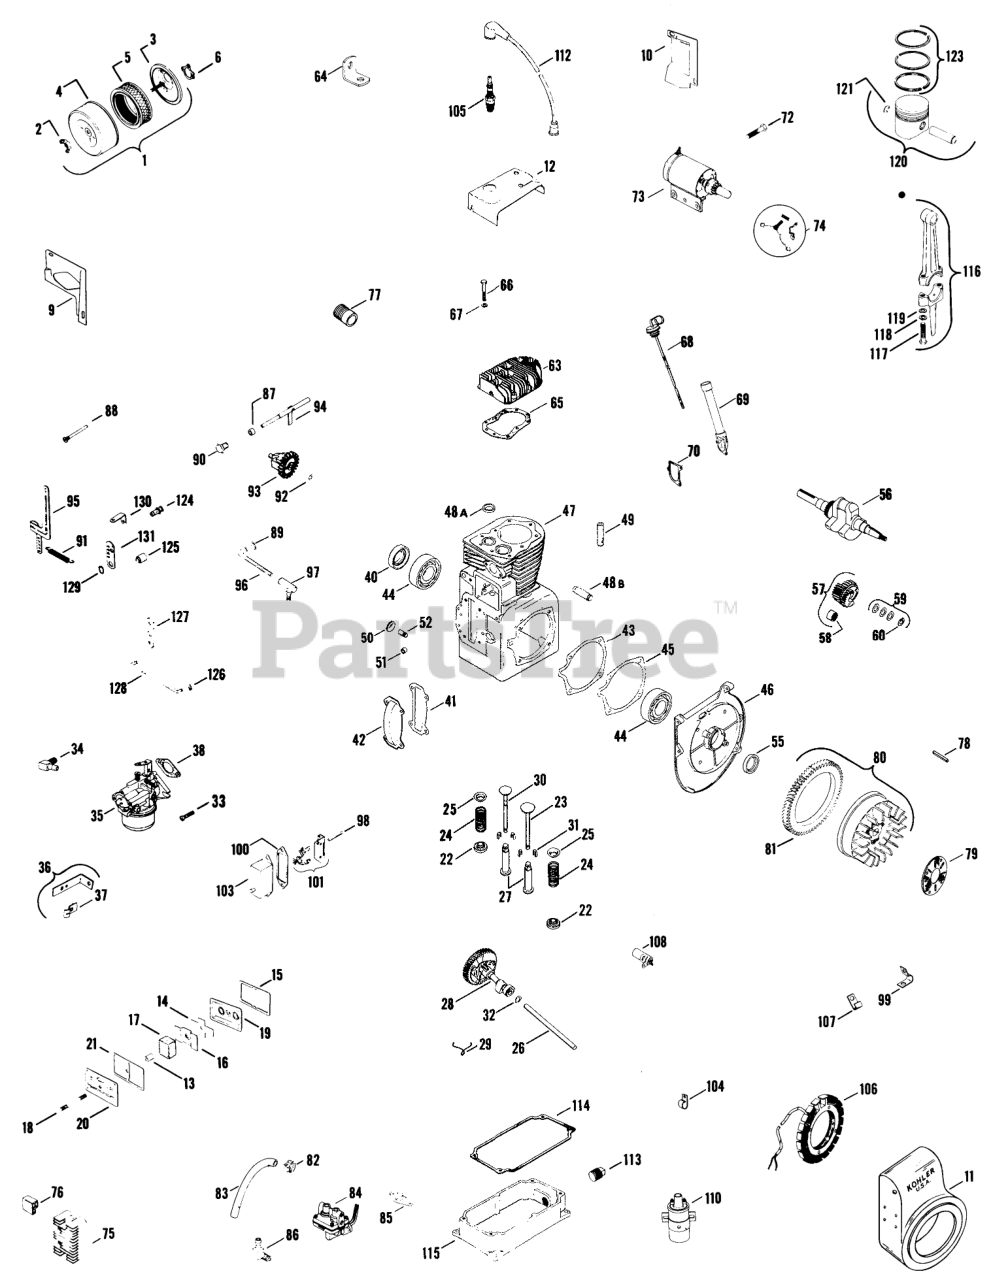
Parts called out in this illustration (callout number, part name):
1	Cleaner-Air Assembly
2	Nut-Wing
3	Base-Air Cleaner
4	Cover-Air Cleaner
5	Element
6	Gasket-Air Horn
9	BaffLe side air
10	Baffle cylinder
11	Housing-Blower
12	Baffle-Head
13	Seal
14	Reed
15	Gasket
16	Baffle breather
17	Filter Breather
18	Stud, valve cover
19	Plate
20	Cover valve
21	Gasket
22	Retainer-Spring
23	Valve-Intake
24	Spring
25	Retainer-Spring
26	Pin (Service)
27	Tappet
28	Camshaft-assembly
29	Spring-Actuating
30	Valve, exhaust
31	Keeper, Valve
32	Spacer
33	Screw sitd. hd.
34	Elbow
35	Carburetor-assembly
35	Repairkit
36	Bracket, choke
37	Clip
38	Gasket
40	Seal rear oil
41	Gasket
42	Cover
43	Gasket
44	Ball Bearing
45	Gasket
46	Plate Bearing
47	Block, cylinder-assembly (Use B-237416 Miniblock)
48A	Insert
48B	Shaft
49	Guide Valve
50	Plug
51	Bearing
52	Shaft-Govemor
55	Seal, Front OiI
56	Crankshaft
57	Gear
58	Bearing,needle
59	Kit-Spacer
60	Retainer
63	Belt Guide
64	Lift Cable
65	Gasket-Head
66	Screw
66	Screw-H.C.
67	Washer
68	Dipstick
69	Tube, fill
70	Gasket
72	Screw
73	Starter
74	Kit, Brush & Spring
75	Regulator
76	Connector
77	Washer
77	Nut
78	Key
79	Screen grass
80	Flywheel-Assembly
81	Gear Ring
82	Clamp
83	Line, fuel
84	Pump, fuel
85	Gasket, pump
86	Elbow
87	Spacer
88	Pin-GovemorStop
89	Retainer Rod
90	Bushing
91	Spring-Governor
92	Washer
93	Gear, governor
94	Shaft, Governor
95	Lever, Governor
96	Rod ball joint
97	Ball Joint
98	Rod, breaker
99	Clip
100	Gasket, Cover
101	Breaker
103	Cover, breaker
104	Clip
105	Plug, spark
106	Stator
107	Clip
108	Condenser
110	Coil
112	Kit, Hi-Tension
113	Plug
114	Gasket
115	Base, oil pan
116	Rod, Connecting
116	Rod-Conn. Assy. (.010)
117	Screw, connecting rod
118	Washer
119	Washer
120	Piston-assembly (Std.)(Includes pin & retainers)
120	Piston-assembly (.003)(Includes pin & retainers)
120	Piston-assembly (.010)(Includes pin & retainers)
120	Piston-assembly (.020)(Includes pin & retainers)
120	Piston-assembly (.030)(Includes pin & retainers)
121	Pin, Retainer
123	Ring set-Std. & .003 (Svc.)
123	Ring set-.010 (Service)
123	Ring set-.020 (Service)
123	Ring set-.030 (Service)
124	Clamp, swivel wire
125	Spacer
126	Retainer Rod
127	Bellcrank
128	Rod, throttle
129	Washer
130	Spacer
131	Bracket
